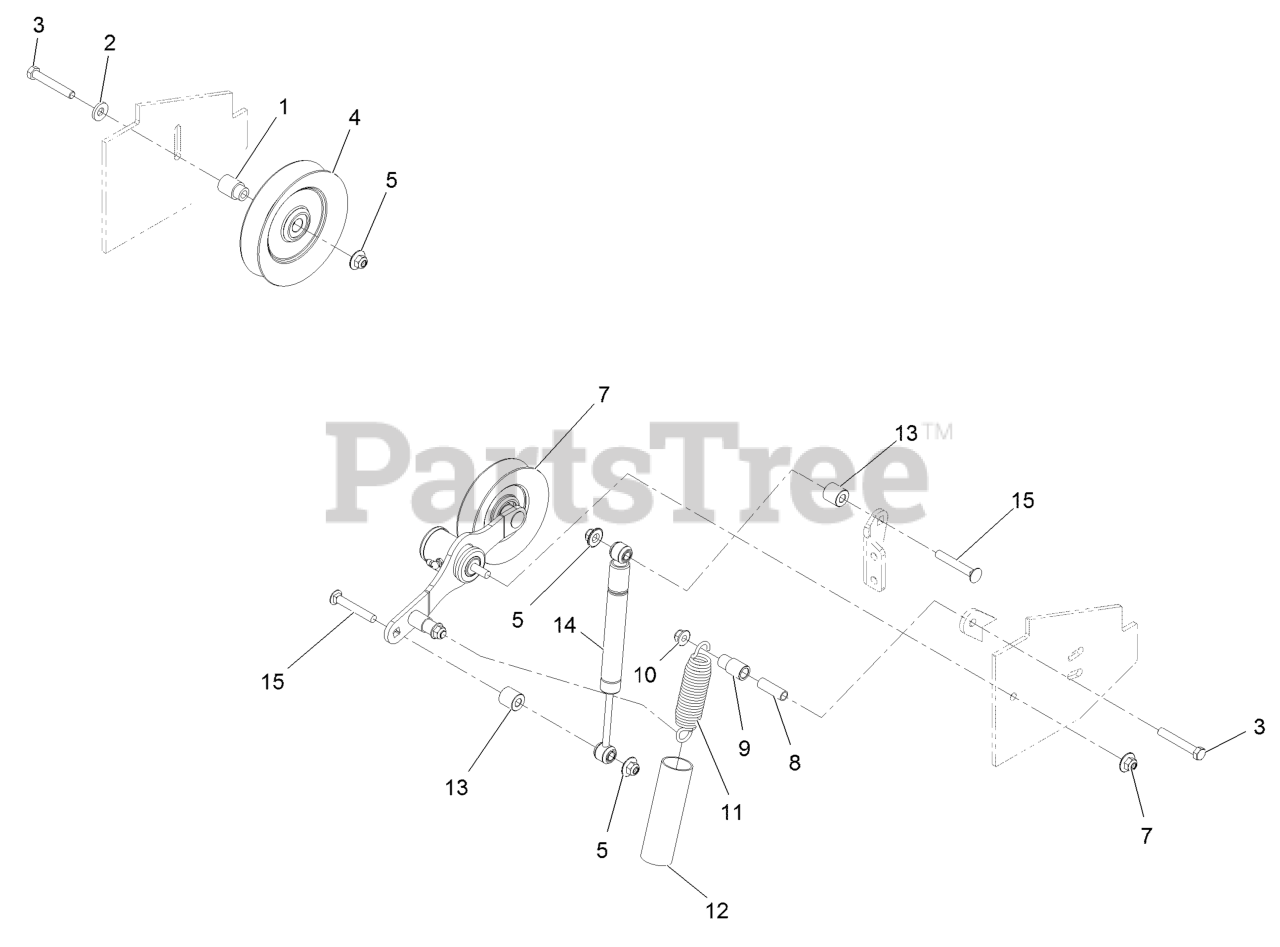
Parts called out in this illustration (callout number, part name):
1	BUSHING-IDLER
2	WASHER-BELLEVILLE
3	BOLT-CARR
4	PULLEY-IDLER
5	Nut-Nyloc 3/8-16 Flg
7	ASM-TTNR ARM W/PULLEY
9	BUSHING,PLASTIC
10	NUT-HF, NI
11	SPRING-EXTENSION
12	DAMPENER,SPRING
13	SPACER-.39IDX.88ODX.88L
14	DAMPER-MULE BELT DRIVE
15	SCREW-CARR
